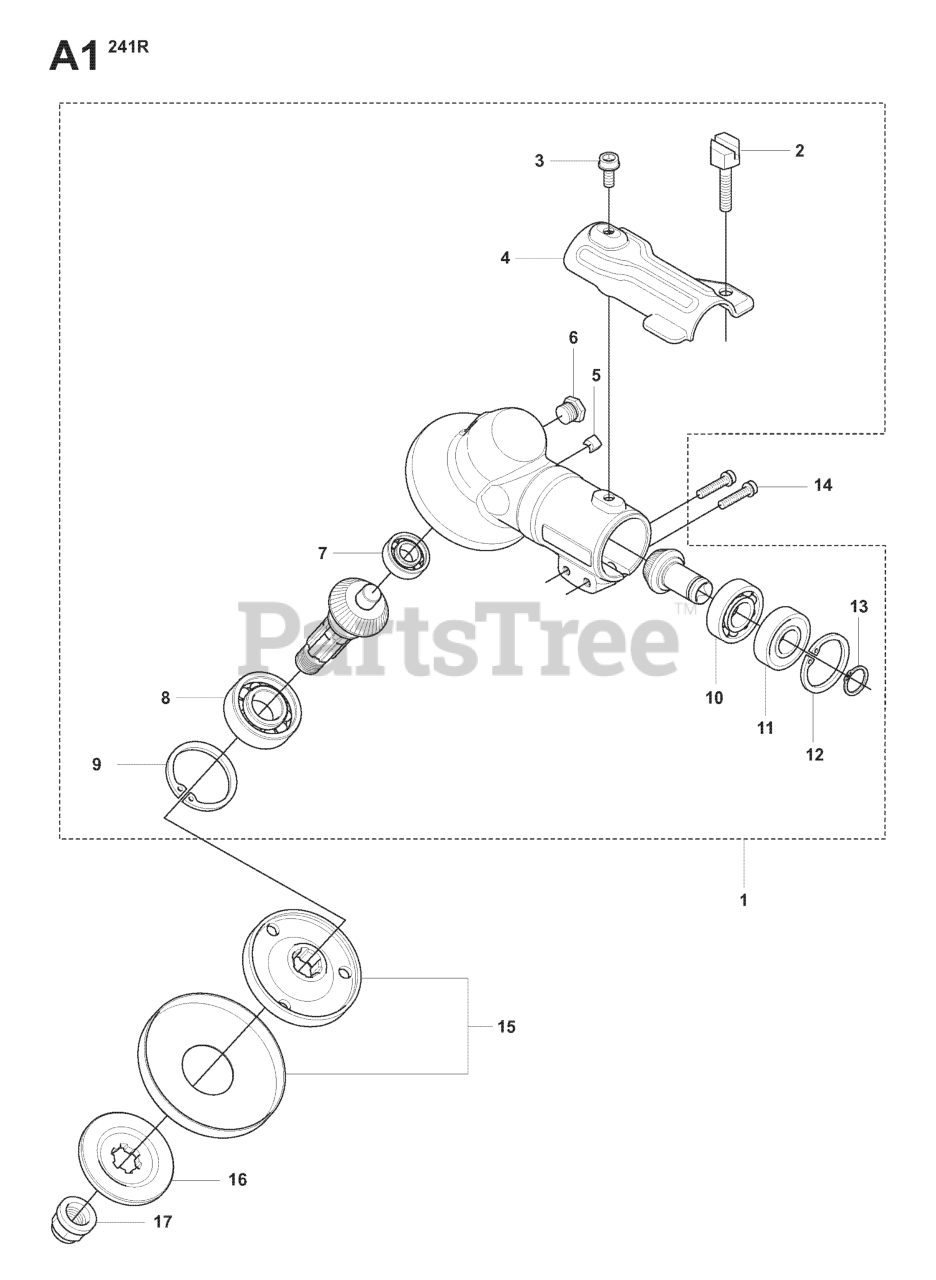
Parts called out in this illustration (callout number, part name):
1	GEAR COMPLETE
3	SCREW
4	RP HOLDER
7	BALL BEARING 24X9X1/609ZR
8	BALL BEARING
9	RETAINING RING
10	BALL BEARING
11	BALL BEARING
12	RETAINING RING SGH 28
13	SEEGER CLIP
15	RP CARRIER
16	RP FLANGE
17	BLADE NUT
